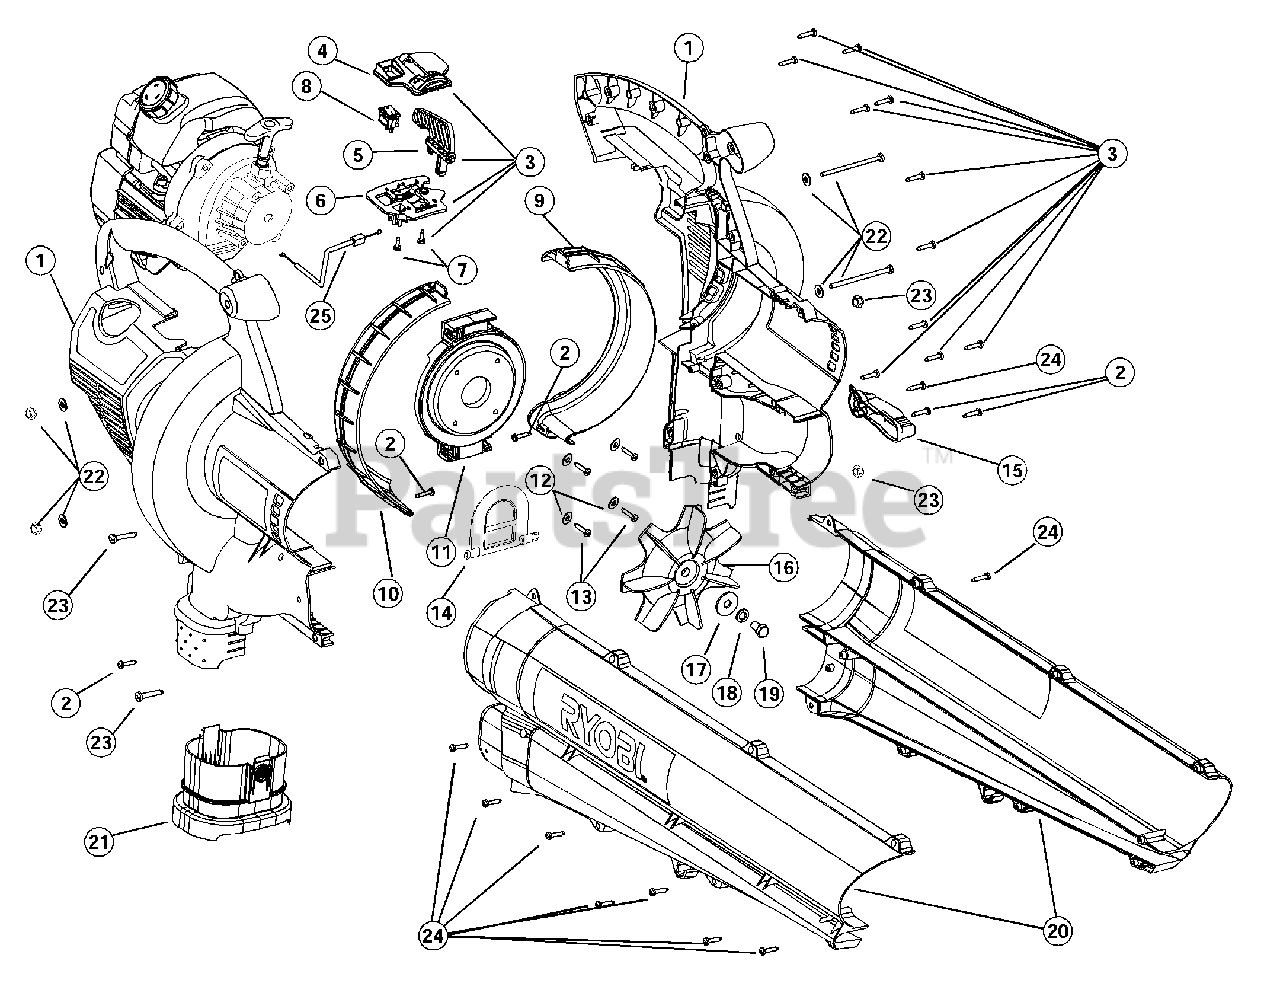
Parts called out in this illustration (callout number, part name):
1	Engine Cover Assembly
2	Cover Screw
3	Throttle Control Assembly
4	Upper Throttle Control Plate
5	Throttle Control Lever
6	Lower Throttle Control Plate
7	Screw, Plastic
8	Rocker Switch Assembly
9	Left Side Liner
10	Right Side Liner
11	Engine Mounting Plate
14	Mode Control Flapper
15	Mode Control Lever
16	Impeller Blade
17	Washer
18	Lock Washer
20	Blower/Vac Tube Assembly
21	Vacuum Bag Adapter
22	Mounting Plate Hardware
23	Blower/Vac Tube Mounting Hardware
25	Throttle Cable
